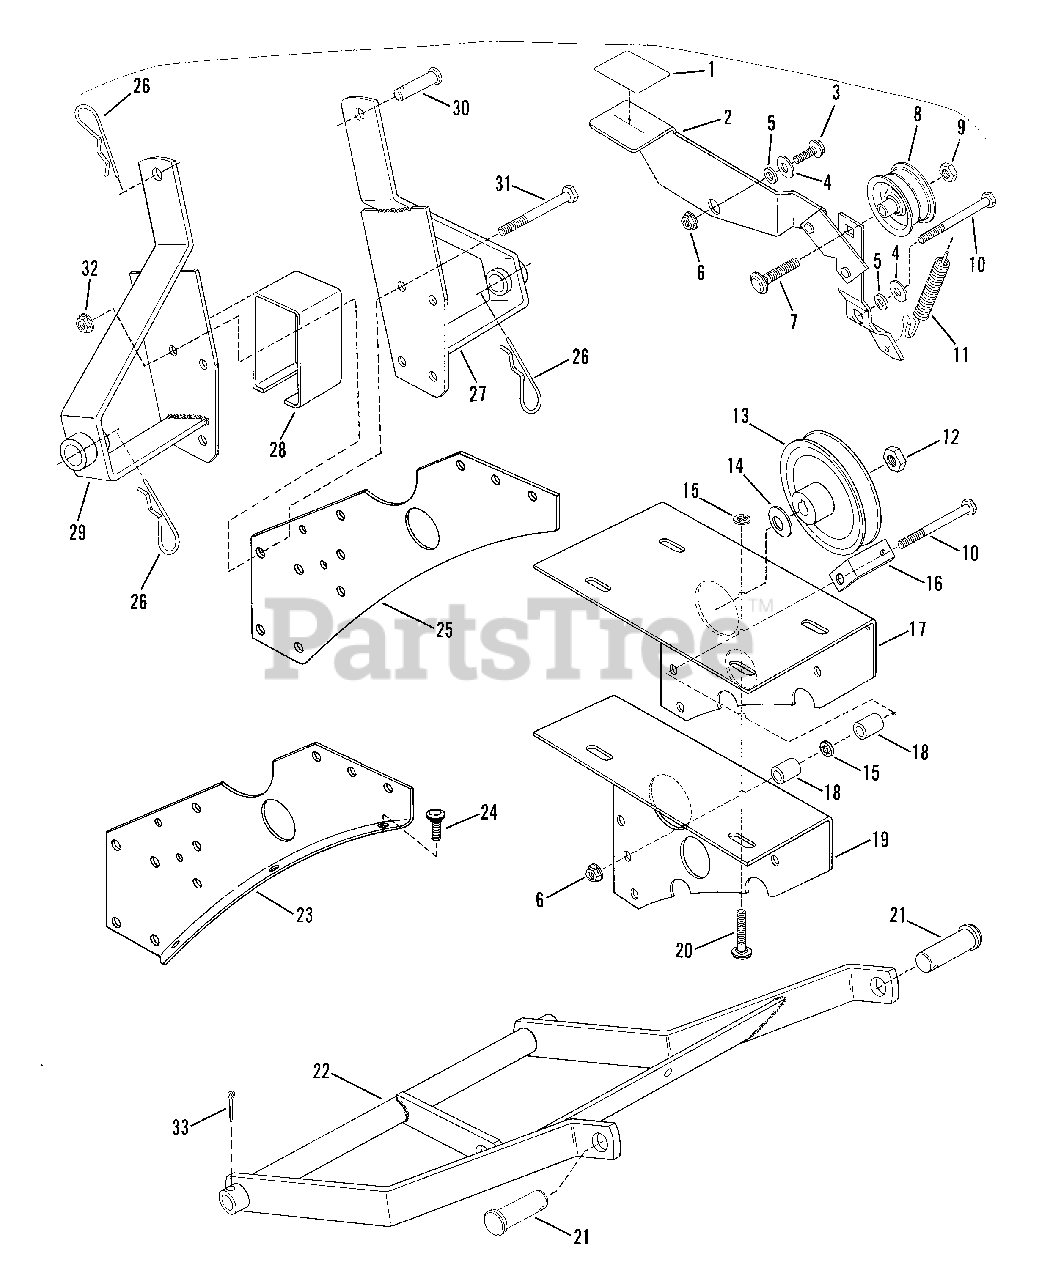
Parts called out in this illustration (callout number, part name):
1	DECAL, Tine Clutch
2	CLUTCH LEVER ASSM'Y
3	BOLT, Lock, 5/16-18x3/4" Hex Flange
4	WASHER
5	SPACER
6	NUT, 5/16-18 Hex Flange Lock
7	BOLT, 3/8-16x1 3/4" Short Neck Carriage
8	IDLER
9	NUT, 318-16 Hex Lock
10	CAPSCREW, 5/16-18x3" Hex Head
11	SPRING, Idler
12	NUT, 5/8-18 Hex
14	WASHER, Cone
15	RETAINER, Bolt
16	BRACKET, Cover
17	MOUNT, Engine (R.H.)
18	SPACER
19	MOUNT, Engine (L.H.)
20	BOLT, 5/16-18x1 3/4" Carriage
21	PIN, 3/4 Clevis
22	ARM, Lift
23	BRACKET, Mounting (L.H.)
24	BOLT, 5/16-18x5/8" Carriage
25	BRACKET, Mounting (R.H.)
26	PIN, Hair
27	HITCH, R.H.
28	SPACER
29	HITCH, L.H.
30	PIN, 1/2 Clevis
31	CAPSCREW, 3/8-16x3" Hex Head
32	NUT, 3/8-16 Hex
33	COTTER PIN
34	CATCH, Over Center
